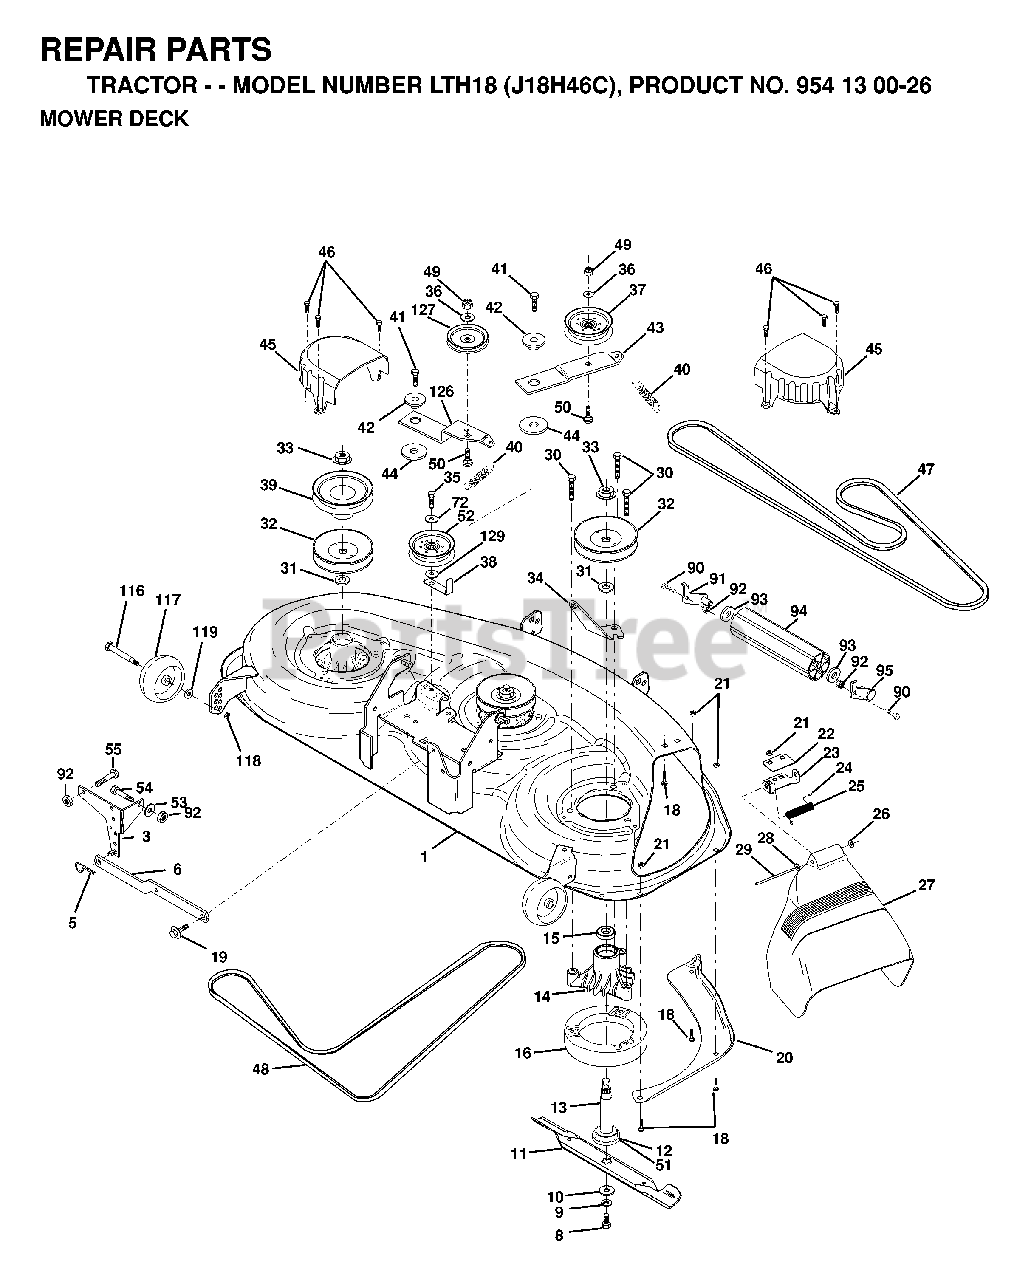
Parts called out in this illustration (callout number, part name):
1	46" MOWER ASSEMBLY
3	BRACKET SWAY BAR
5	RETAINER-SPRNG RB
6	REAR SUSP ARM
8	BLADE BOLT
9	LOCKWASHER
10	WASHER.BLADE
11	BLADE HIGH LIFT
12	BEARING
13	SHAFT.ASM.W/BEARING
14	HOUSING.MANDREL
16	STRIPPER
18	BOLT
19	BOLT SHD 5/16-18
20	BAFFLE, VORTEX MOWER 46"
21	LOCKNUT
22	STIFFENER BRACKET
23	DEFLECTOR BRACKET
24	CAP-SLEEVE LT
25	TORSION SPRING
26	NUT PUSH M
27	DEFLECTOR SHIELD
28	WASHER
29	ROD.HINGE
30	SCREW THDROL ROLLING WASHER HD
31	WASHER
32	PULLEY, MANDREL
33	NUT
34	ANCHOR, SPRING DECK 46"
35	SCREW LT
37	FLAT IDLER PULLEY
38	KEEPER.BELT.IDLER
39	PULLEY.DRIVEN.DECK.46"
40	SPRING.SEC.44"VEN
41	SCREW
42	SPACER RETAINER
43	ARM IDLER DECK 46"
44	HARDENED WASHER
45	COVER MANDREL 46
46	SCREW.1/4-20X5/8
47	BELT V SECONDARY
48	V-BELT PRIMARY 50"
49	LOCKNUT
50	BOLT.3/8-16X1.50
51	WASHER FELT
52	PULLEY IDLER FLAT 46 PRI DRIVE
53	WASHER
55	BOLT D
90	BOLT
91	BRACKET LH (A)
92	NUT
94	NOSE ROLLER
95	BRACKET RH (B)
118	LOCKNUT
119	WASHER
126	ARM IDLER PRIM 46
127	PULLEY.IDLER.4.25
129	WASHER GT
